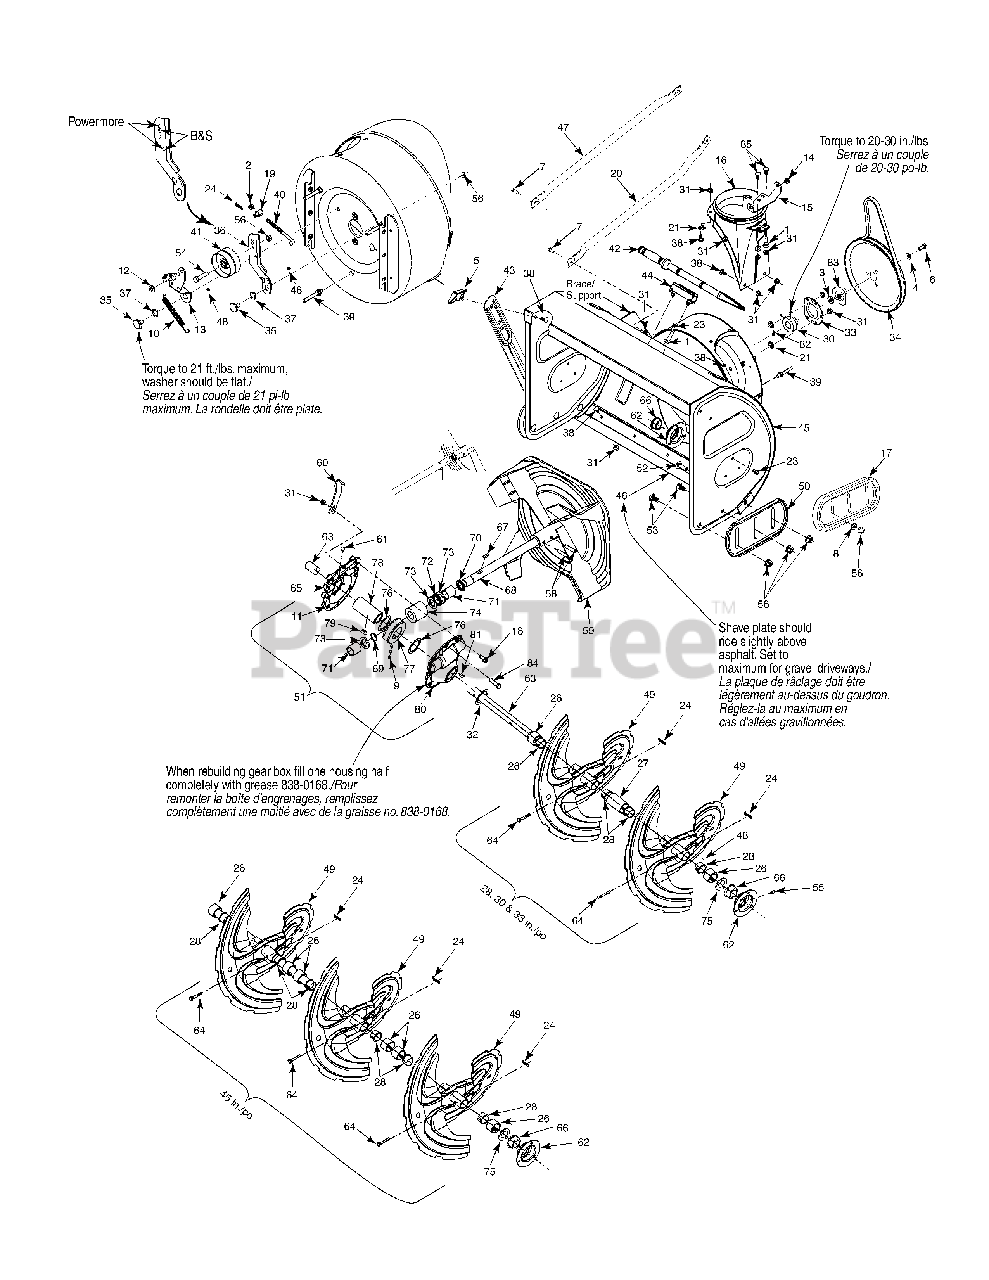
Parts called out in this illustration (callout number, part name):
1	Flat Washer .349 ID x .879 OD x .063
2	Hex Jam Nut 5/16-18 Gr. 5
3	Flat Washer .760 ID x 1.49 OD
4	Flat Washer .34 x 1.5 x .150
5	Handle Knob Assembly
6	Hex Screw 5/16-24 x .875 Gr. 8 Lock
7	Hex Hd Cap Scr. 5/16-18 x .75 Gr. 5
8	Flat Washer .385 x .870 x .092
9	Alvania Grease
10	Extension Spring .470 Dia. x 4.75
11	Ultra Grey Loctite #5699
12	Flat Washer .344 ID x .75 OD x .120
13	Brake Bracket Ass’y (900 Series)
14	Plastic Bushing .380 ID
16	Chute Adapter
17	Reversible Slide Shoe (Plastic)
18	Screw, 5/16-18 x .5
19	Adjustment Ferrule
20	Support Tubing RH (w/Plastic panel)
20	Support Tubing LH (w/Plastic panel)
21	Push-on Nut .25 diam
23	Hex TT Screw 5/16-18 x .75
24	Bow Tie Cotter Pin
26	Spacer 1.5 x 1.0 ID x 1.0" Lg.
27	Spacer 1.5 x 1.0 ID x 2.5" Lg.
28	Flange Bushing 1.05 ID x 1.16 OD
30	Self-Aligning Bearing .875 ID
31	Hex Flg. L-Nut 5/16-18 Gr. F Nylon
32	Flat Washer 1.010 x 1.88 x .060
33	Bearing Housing
34	Pulley .5 ID x 10 OD
35	Shoulder Scr .625 Dia x .170
36	Auger Idler Bracket
37	Wave Washer .625 ID x .885 OD x .015
38	Carriage Bolt 5/16-18 x .75
39	Screw 5/16-18 x .43 (w/stud)
40	Auger Idler Rod
41	Flat Idler Pulley
42	Cleanout Tool
44	Cleanout Tool Mount
45	Auger Housing 28" - Yellow
46	Shave Plate 28" - Yellow
47	Support Tubing (w/steel panel)
48	Arctic Grease
49	Augers LH - Yellow
49	Augers RH - Yellow
51	Worm Gear Box Ass’y (w/o grease Fitting)
51	Worm Gear Box Ass’y (w/ grease Fitting)
52	Carriage Bolt 3/8-16 x 1.00" (w/steel shoe)
52	Carriage Bolt 3/8-16 x 1.25" (w/Plastic shoe)
53	Carriage Bolt 3/8-16 x .75" (w/steel shoe)
53	Carriage Bolt 3/8-16 x 1.00" (w/Plastic shoe)
54	Hex Hd. Cap Scr 3/8-16 x 1.75 Gr. 5
55	Grease Fitting
56	Hex Flange L-Nut 3/8-16 Gr. F Nylon
58	Spring Spirol Pin Heavy - 5/16 dia x 1.7
59	Blower Fan Ass’y Complete
60	Gear Housing Support Bracket
61	Barbed Plug
63	Auger Shaft 28"
63	Auger Shaft 30"
63	Auger Shaft 33"
63	Auger Shaft 45"
64	Shear Pin 5/16-18 x 1.75
65	Gear Housing Half - RH
66	Flange Bearing
67	#9 HI-Pro Key 3/16 x 3/4 Dia HT
68	Auger Drive Shaft
69	Snap Ring for .875 dia. shaft
70	Oil seal for .875 ID Garlock (76 x 6133)
71	Sleeve Bearing .875 ID
72	Thrust Bearing .88 ID x 1.44 OD x .078
73	Flat Washer .88 ID x 1.4 OD x .125
74	Worm Gear LH Double Thread
76	Flat Washer 1.5 ID x 2.0 OD x .03
77	Worm Gear LH Double Thread (Bronze)
78	Worm Gear Shaft
79	#91 Woodruff Key 1/4 x 3/4 Dia.
80	Gear Housing Half LH
80	Gear Housing Half LH (w/grease Fitting hole)
81	#91 Wood ruff Key 1/4 x 3/4 Dia.
82	Low Temperature grease
83	Pulley Adapter .75 Dia. w/pins
84	Hex Hd. Cap Scr. 5/16-18 x 1.0 Gr. 5
85	Carriage Bolt 5/16-18 x 1.00" Lg
